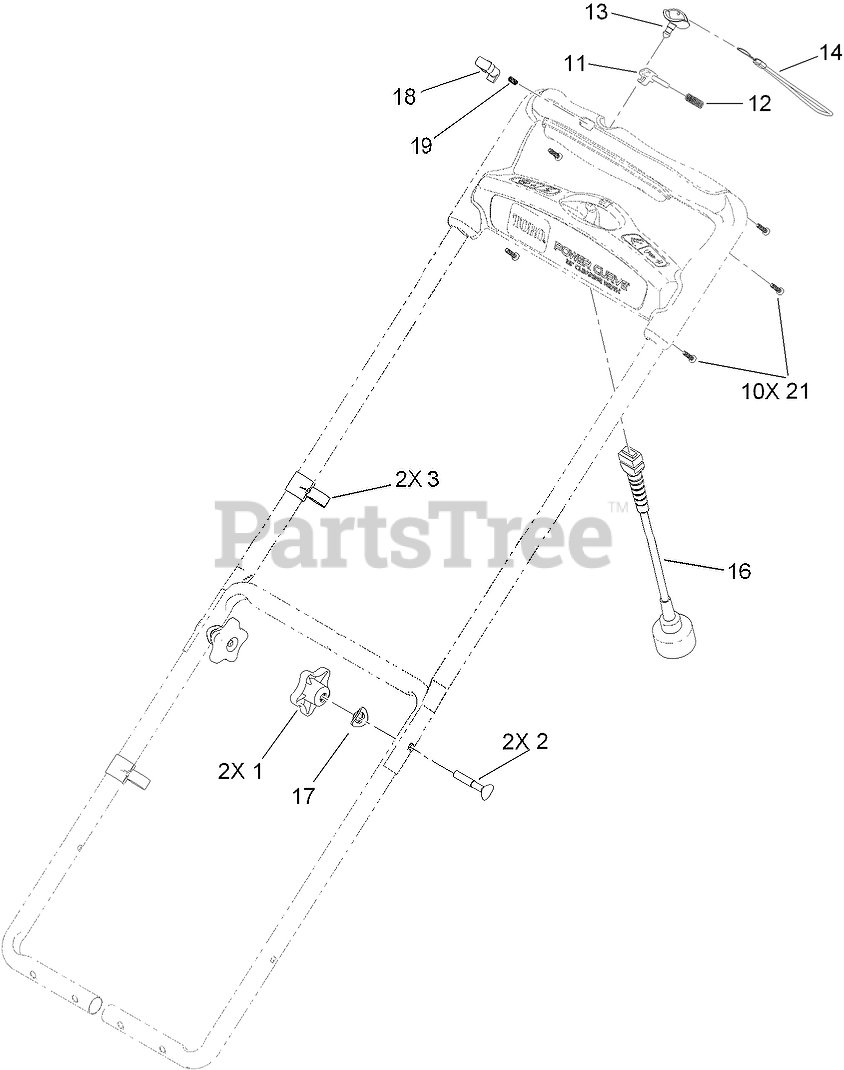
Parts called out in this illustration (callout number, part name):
1	KNOB-HANDLE
2	SCREW-HANDLE
3	GUIDE-CABLE
11	LOCKOUT-BAR, CONTROL
12	SPRING-LOCKOUT
14	CORD-KEY
16	WIRE ASM
17	WASHER
18	BUTTON-SAFETY
19	SPRING-COMPRESSION, SAFETY
21	SCREW-NON SERVICEABLE
